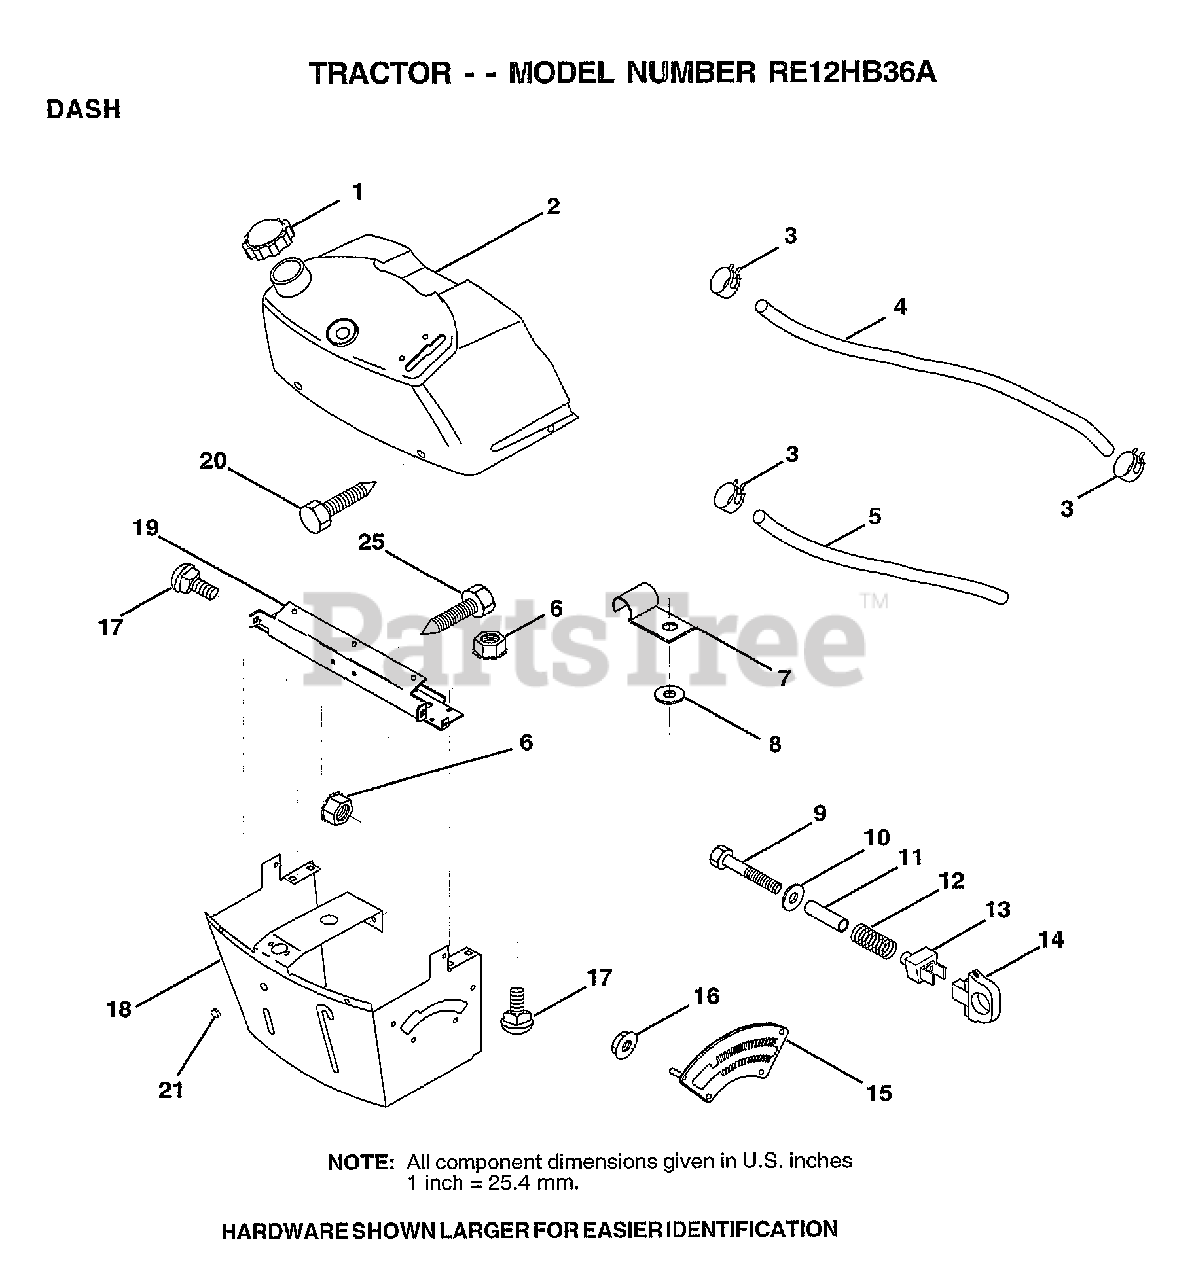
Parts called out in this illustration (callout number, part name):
1	CAP BLK FUEL LR
2	TANK.ASM.DASH.LR
3	HOSE CLAMP
5	FUEL LINE T
6	NUT HXKEP 1/4X20
7	CLIP T
8	WASHER PM
9	BOLT
11	SPACER SPLIT
12	SPRING M
13	"KNOB,HGT RETAINER"
14	KNOB
15	ADJUSTER QUAD
16	NUT
17	BOLT
18	SUPT ASSY DASH
19	CROSS BRACE
20	SCREW.1/4-20X1/2
21	PLUG DOME
25	SCREW LT
